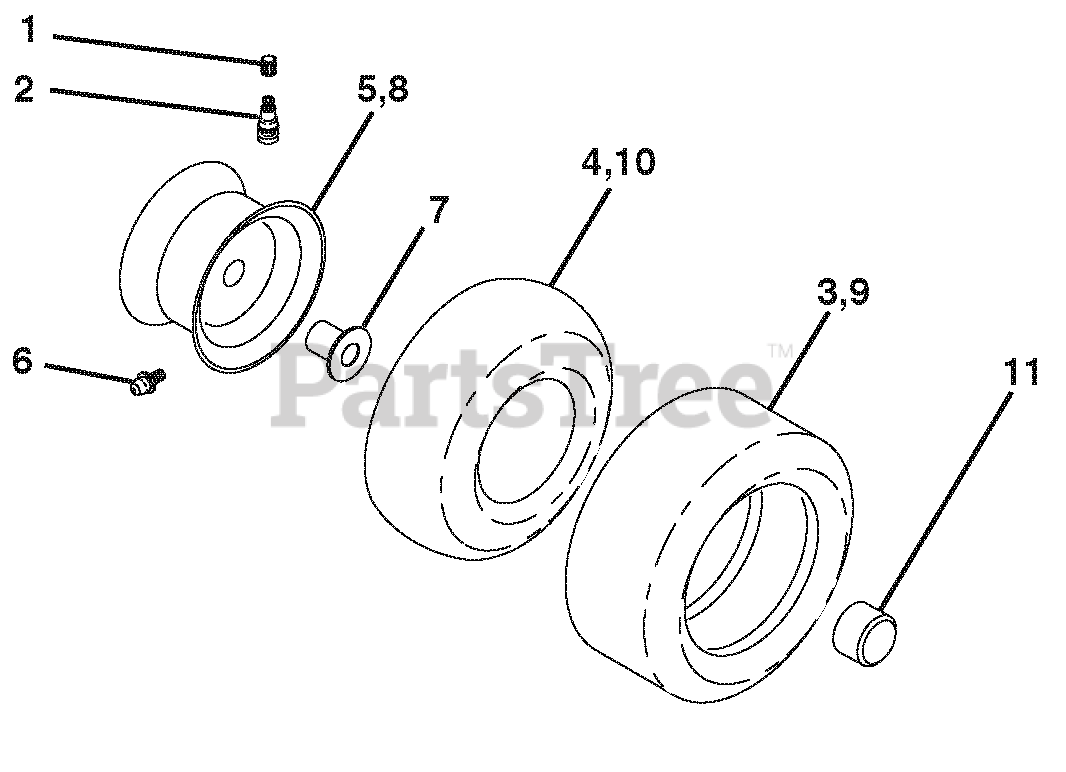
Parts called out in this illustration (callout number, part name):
1	CAP.VALVE.TIRE
2	STEM.VALVE
3	TIRE.F.TS.15 X 6.0 - 6.SERVICE
4	TUBE.INNER.FRONT.#35060
5	RIM ASSEMBLY 6" FRONT
6	FITTING, GREASE
7	BEARING FLANGE
8	RIM ASSEMBLY 8" REAR
9	TIRE.R.TS.20 X 8-8.C.SERVICE
10	TUBE, REAR
11	CAP AXLE (FRONT WHEEL ONLY)
